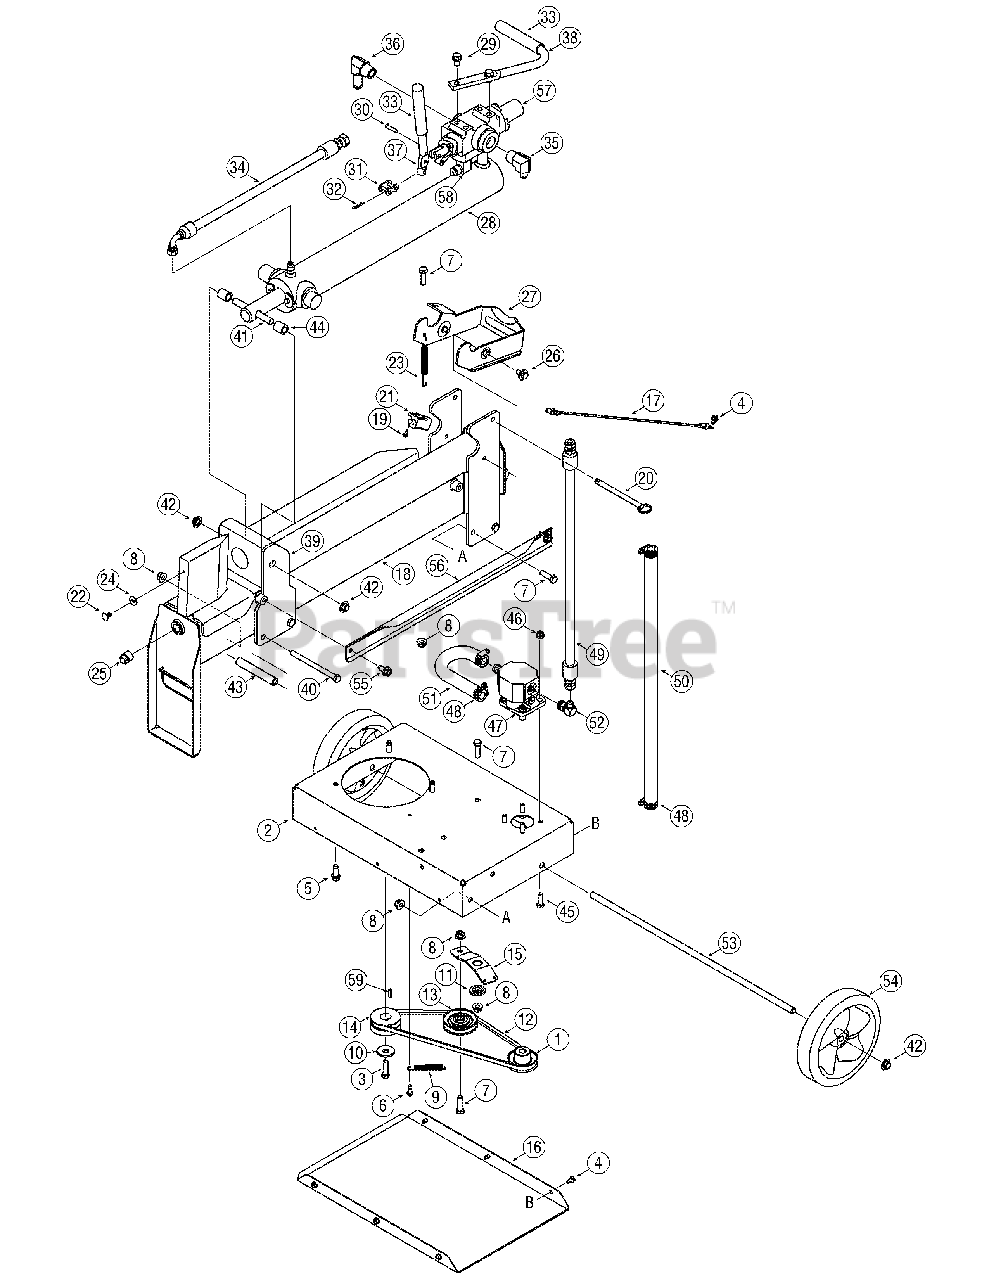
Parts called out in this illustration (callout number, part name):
1	Pulley, .50 ID x 2.38 OD
3	Screw, 3/8-24 x 1.25
4	Tt Screw, 1/4-20 x .375
5	Tt Screw, 3/8-16 x 1.00
6	Screw, Shldr., .30 x .46
7	Screw, 3/8-16 x 1.25
8	Nut, Flange Lock, 3/8-16
9	Spring, Extension, .375 x 2.95
10	Washer, Bell, .396 x 1.140 x .095
11	Spacer, Shldr., .38 x .75 x .13
12	Belt, V-Type, 3L, 33.92"
13	Pulley, V-Idler, 2 x 2.75 x .625-3L
14	Pulley, Idler
17	Harness, Interlock
19	Shoulder Screw, #10-16 x .500
20	Pin, Locking
21	Switch, Interlock
23	Spring, Extension, .480 OD x 5.0
24	Washer, Slotted, Felt
25	Plug, Drain
26	Screw, Shldr., .560 x .165
28	Cylinder
28	Kit, Seal 2.5" Cylinder
29	Screw, 3/8-16 x .625
30	Pin, Clevis
31	Link, Handle, Valve
32	Pin, Cotter
34	Hose, Valve, Cylinder
35	Adapter, Hydraulic
36	Adapter, Hydraulic
37	Control, Valve, Hydraulic
40	Screw, 3/8-16 x .500
41	Rod, Pivot, .497 x 4.160
42	Cap, Push
43	Spacer, .385 x .625 x 4.07
44	Spacer, .525 x .775 x .852
45	Screw, 5/16-18
46	Nut, Flange Lock, 5/16-18
47	Pump, Gear
48	Clamp, Hose
50	Hose, Return
51	Hose, Inlet
52	Fitting, Elbow
54	Wheel
55	Tt Screw, 5/16-18 x .750
57	Valve
58	Adapter
